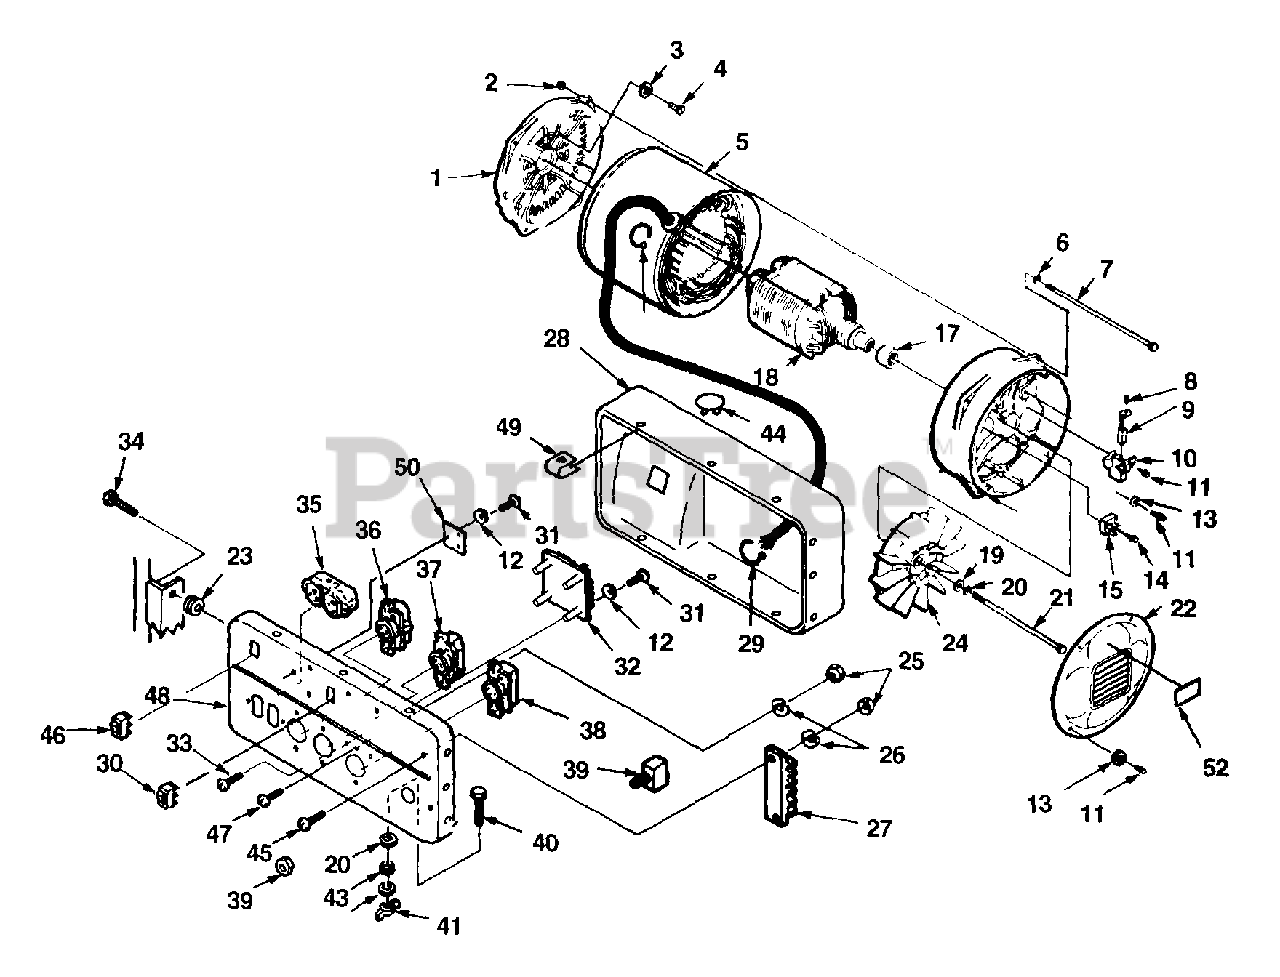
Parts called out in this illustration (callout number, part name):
1	END BELL
2	NUT-Hex (1/4-20)
3	WASHER-Lock
4	SCREW-Hex Hd (3/8-16 X 7/8")
5	STATOR SHELL
6	WASHER-Lock/int (1/4")
7	BOLT-Stator
8	SCREW-Mach Pan Hd (8-32 X 3/8")
10	BRUSH HOLDER
11	SCREW-Thread Rolling (8-32 X 1/2")
12	WASHER-Flat (#8)
13	WASHER-Lock (#8)
14	SCREW-Hex Tap (8-32 X 3/4")
15	RECTIFIER
17	BEARING
19	WASHER-Flat (5/16)
20	WASHER-Lock (5/16)
21	BOLT-Rotor
22	BRUSH HEAD COVER
23	GROMMET
25	NUT-Hex (8-32)
26	WASHER-Lock (#8)
27	BLOCK-Terminal
28	PANEL-Cover
29	CABLE TIE
30	SWITCH (DPDT)
31	SCREW-Pan Hd (#8-32 X 1/2")
32	VOLTAGE REGULATOR
33	SCREW- Plastite (8-16 x 1")
34	SCREW-Shoulder
35	RECEPTACLE, GFCI (Nema 5-15R)
36	RECEPTACLE-Locking (Nema L5-20R)
37	RECEPTACLE-Locking (Nema L5-30R)
38	RECEPTACLE-Locking (Nema L14-20R)
39	CIRCUIT BREAKER-3.0 Amp
40	SCREW-Hex Md (5/16-18 X 1")
41	NUT-Wing (5/16-18)
43	NUT-Hex (5/16-18)
44	CLAMP-Cable
45	SCREW-Pan Hd (8/32 X 5/8")
46	SWITCH-Rocker
47	SCREW-Machine Pan (8-32 X 3/8")
48	CONTROL PANEL
49	DECAL-Schematic
50	IDLE CONTROL
52	DECAL-Warning
